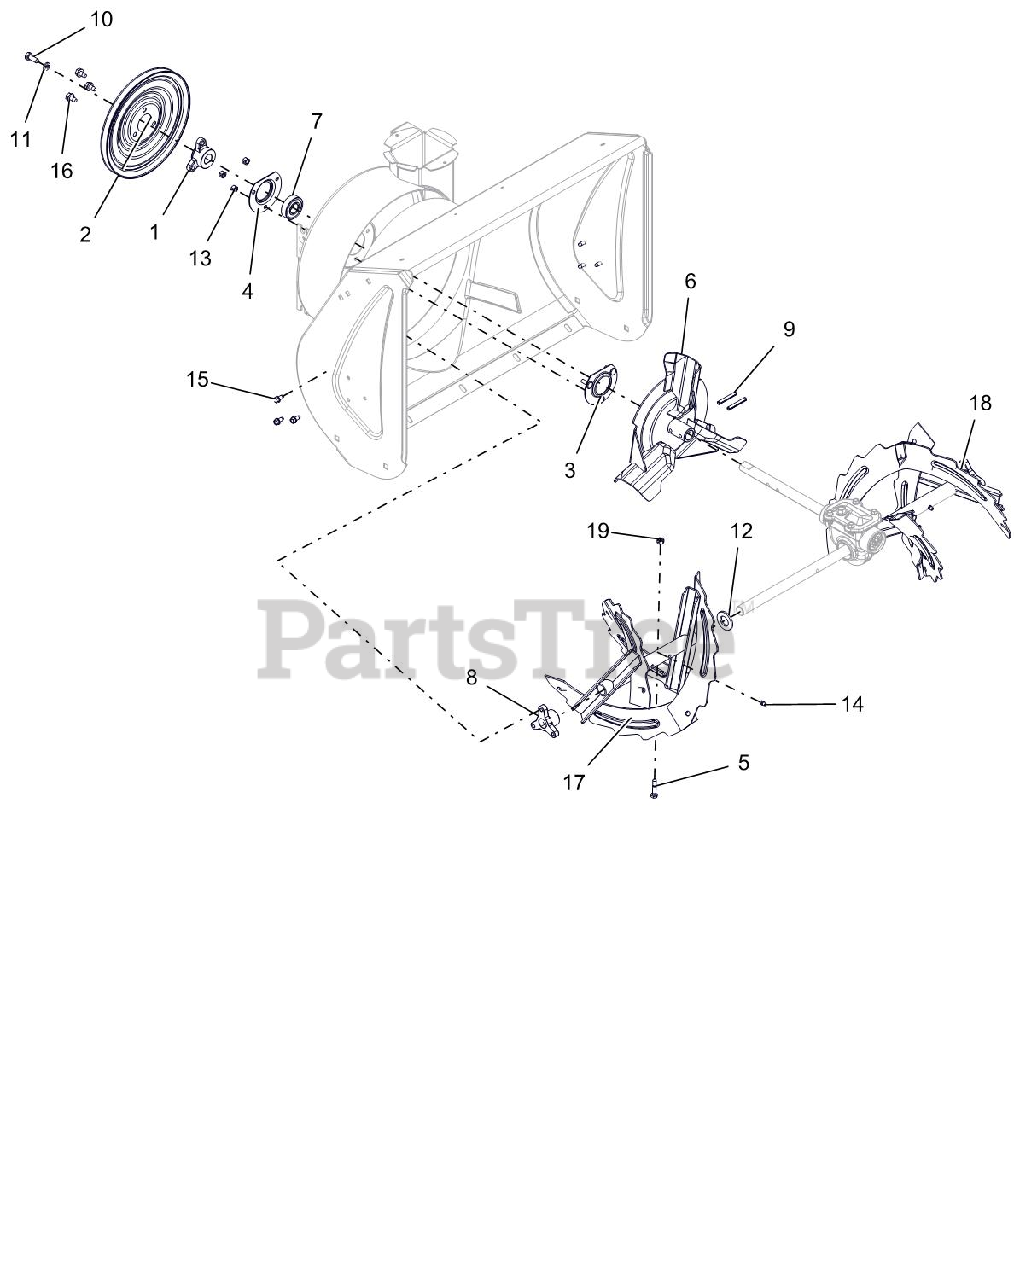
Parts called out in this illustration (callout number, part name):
1	PULLEY HUB, BOLT-ON D-BORE .75
2	PULLEY,SPIN FORM SINGLE GROOVE
3	BEARING FLANGE
4	BEARING FLANGE
5	SHEAR BOLT WITH NUT
6	IMPELLER, COMPACT 12" 3-BLADE
7	BRG-BALL .750X1.750X.50
8	BUSHING, RAKE SHAFT .75"
9	PIN-ROLL .250X1.75
10	BLT-HEX .31-24X.75 YWZC GR5
11	WSHR-LK .312X.097 HVY YWZC
12	@WSHR-FL-STL.812X1.50X.135YWZC
13	@NUT-LK-CTR .25-20 YWZC
14	ZERK,FITTING .25X.125 DRIVE IN
15	SCR-TAP .25-20X.50 HWH TR YWZ
16	@SCR-TAP .31-18X.50 HWH TR YWZ
17	RAKE, 24" RH, BLK SERR W/ZERK
18	RAKE, 24" LH, BLK SERR W/ZERK
19	@NUT-LK-CTR .25-20 YWZC
